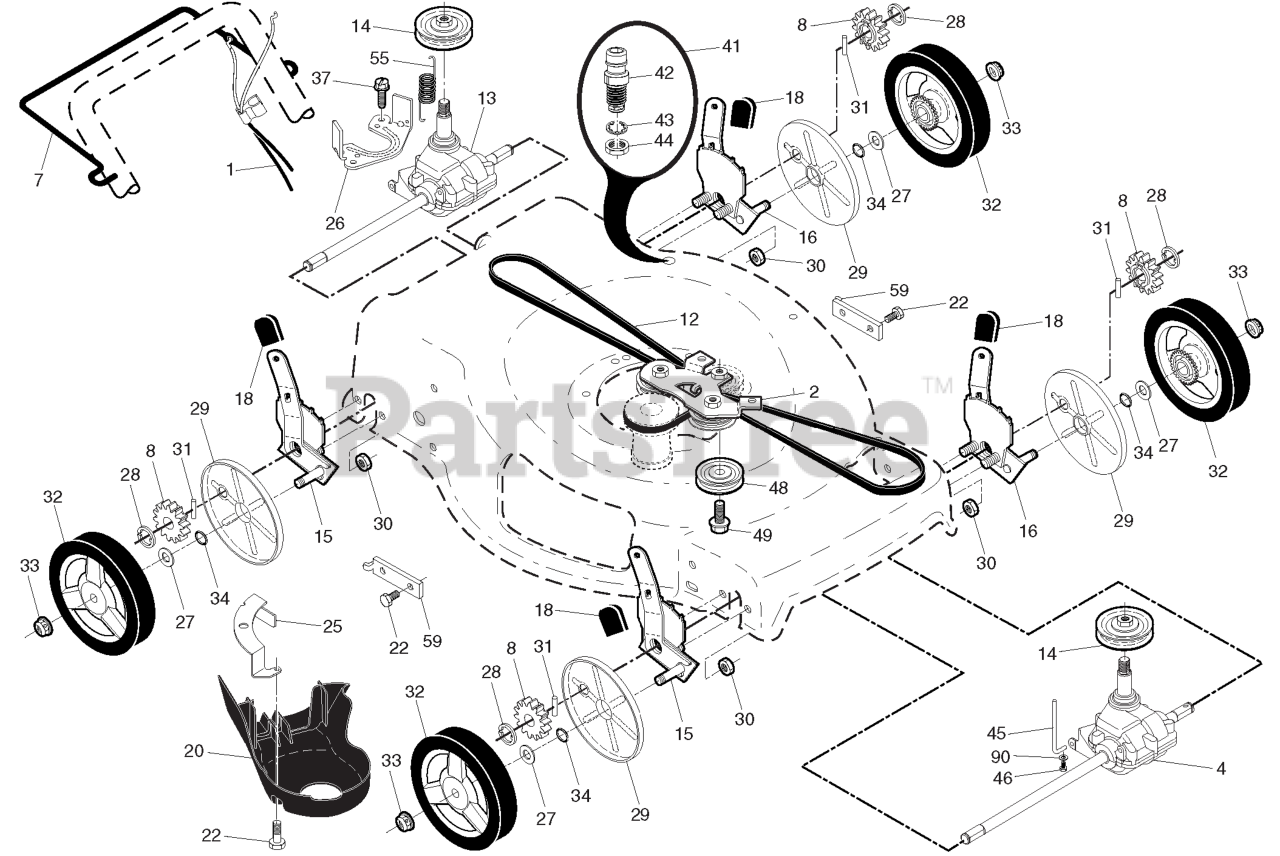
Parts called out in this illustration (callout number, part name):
1	CABLE.DRIVE.UB.AWD
2	BRACKET.ASM.AWD.BZP.BLACK
4	RP.TRANSMISSION.22+.AWD.FRONT
7	BAIL.CONT.DR.S/S.ROUND.BLACK
8	PINIION.14.TOOTH.RGD
12	BELT.DRIVE.AWD.PLUS.13
13	TRANMISSION.ASM.22+AWD.REAR.14
14	RP PULLEY.PM.22+AWD
15	ADJUSTER.ASM.22+FGD.RF /AWD RT
16	ADJUSTER.ASM.22+FGD.LF /AWD LT
18	SELECTOR KNOB
20	COVER.REAR.DRIVE.22+2013
22	BOLT.5/16HEX.WHS.HD
25	BRACKET.DRIVE.COVER.RGD.BZP
26	BRACKET.TRAN.BELTKEEPER.22+RGD
27	WASHER FLUT
28	E-RING 7/16 RE
29	COVER.DUST.WHEEL.INNER.WALK
30	NUT.FLANGE.1-4-20-SERR
31	PAWL, DRIVE
32	WHEEL.8".AWD.3SP.EXT.DR.GREY
33	NUT.HEX.FLANGE.3/8-16.LO(3 2)
34	O-RING..070X.487.NEOPRENE
41	KIT.WASH-OUT.PORT
42	FITTING, HOSE, WATER WASHOUT
43	WASHER.LOCK.INTERNAL.TOOTH
44	LOCKNUT.HEX.WITH.O-RING
45	BRACKET.AWD.FRONT.BELT.KEEPER
46	SCREW.HI-LO. 5/16 X 1.00
48	RP PULLEY.IDLER.ASM
55	SPRING.RETURN.AUTO.
59	BRACKET.SUPPORT.22+RWGD.BZP
90	WASHER 5/16 FLAT
